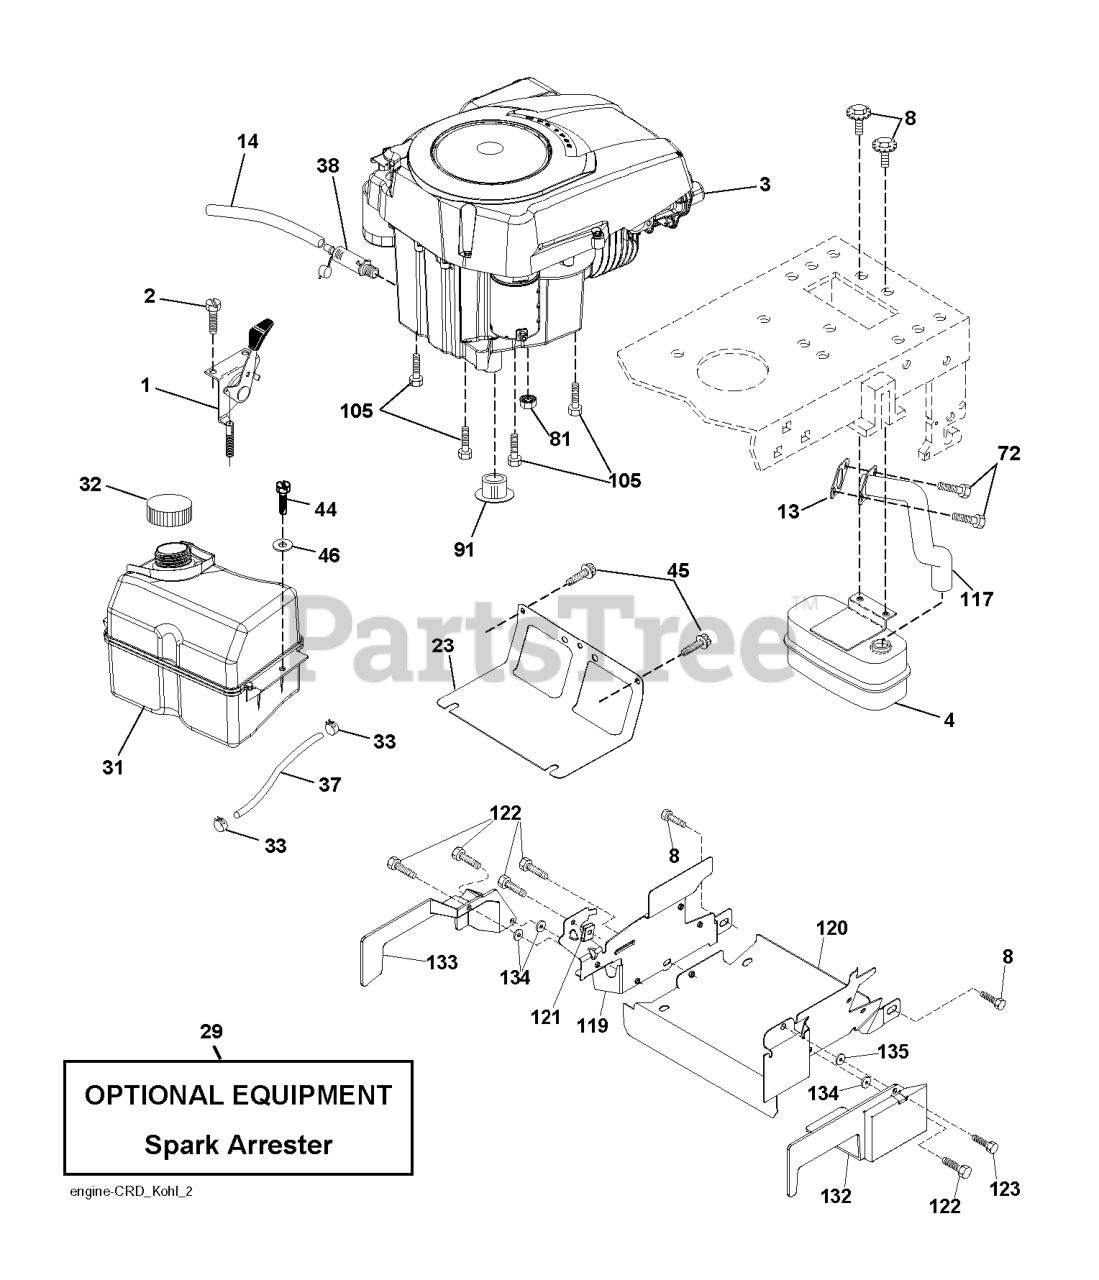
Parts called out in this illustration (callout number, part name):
1	CONTROL.TH/CK.C.
2	SCREW.#10 X 0.750.BOS
4	MUFFLER.SINGLE.CYL.KOHL/B&S
8	BOLT.5/16-18UNCX3/4 W/SEMS.BLK
13	GASKET.EXHAUST.KOHLER
14	TUBE, DRAIN OIL ASM.
23	SHIELD.BROWNING.DBR.GUARD
29	KIT.SPARK ARRESTOR 794945 B&S
31	RP TANK FUEL FRT 1.5 GAL
32	FUEL CAP
33	HOSE CLAMP
37	LINE.FUEL.20
38	PLUG DRAIN OIL EASY
44	SCREW HEXWSHR 1/4-20X3/4
45	SCREW, 3/8-16X3/4
72	SCREW.SOCKET HD.5/16-1
81	NUT
91	BUSHING.1.375OD
105	SCREW 3/8-16X1
117	RP.TUBE.EXHAUST.KOHL.COURAGE
119	LENKRAD
120	GUARD 532199767
122	SCREW.1/4-20X5/8
123	SCREW, 5/16-18 X 1/2
132	SHIELD RIGHT
133	SHIELD LEFT
134	PALNUT 1/4
135	WASHER 5/16"
